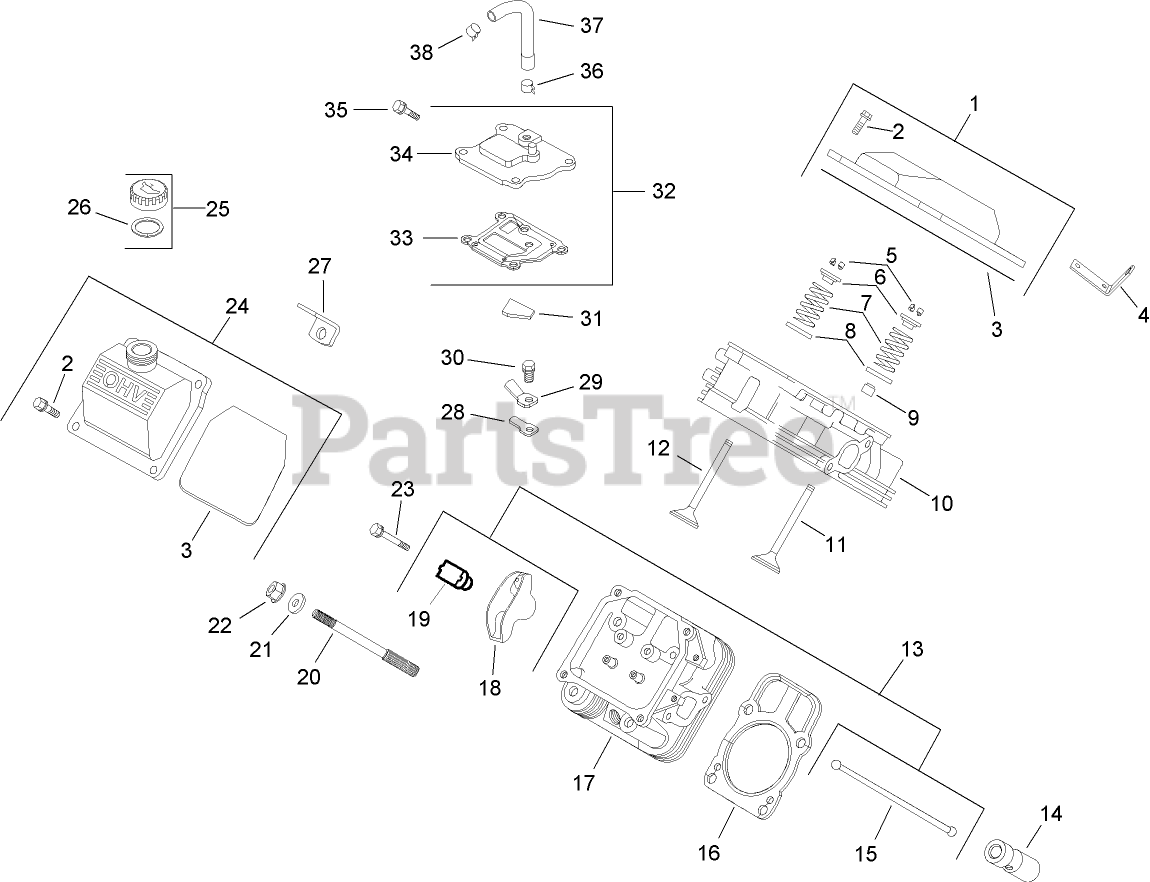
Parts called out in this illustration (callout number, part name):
1	PLAIN ROCKER COVER KIT
2	SCREW-FLANGE (M6X1.0X30)
3	O-Ring
4	STRAP-LIFTING
5	RETAINER KIT
6	CAP-SPRING, VALVE
7	SPRING-VALVE
8	RETAINER-SPRING
9	SEAL-STEM, VALVE
10	CYLINDER HEAD ASM
11	VALVE-INTAKE (STD)
11	VALVE-INTAKE (.25)
12	VALVE-EXHAUST (STD)
12	VALVE-EXHAUST (.25)
13	VALVE TRAIN KIT
14	HYDRAULIC VALVE LIFTER KIT
15	ROD-PUSH
16	CYLINDER HEAD GASKET KIT
17	CYLINDER HEAD ASM
18	ARM-ROCKER
19	PIVOT-ARM, ROCKER
20	STUD (M8X1.25xM10X1.5x105MM)
21	WASHER-FLAT (8.6 MM)
22	NUT-FLANGE (M8X1.25)
23	SCREW-FLANGE (M6X1.0X34)
24	OIL FILL ROCKER COVER KIT
25	Oil Fill Cap ASM
26	O-RING
27	Strap-Lifting
28	REED-BREATHER
29	RETAINER-REED
30	SCREW-HHFTF (M5X.80X10)
31	Filter-Breather
32	BREATHER ASM
33	GASKET-BREATHER
34	COVER-BREATHER
35	SCREW-HHFTF (M6X1.0X20)
36	Clamp-Hose
37	Hose-Breather
38	CLAMP-HOSE, SPRING (1/2)
